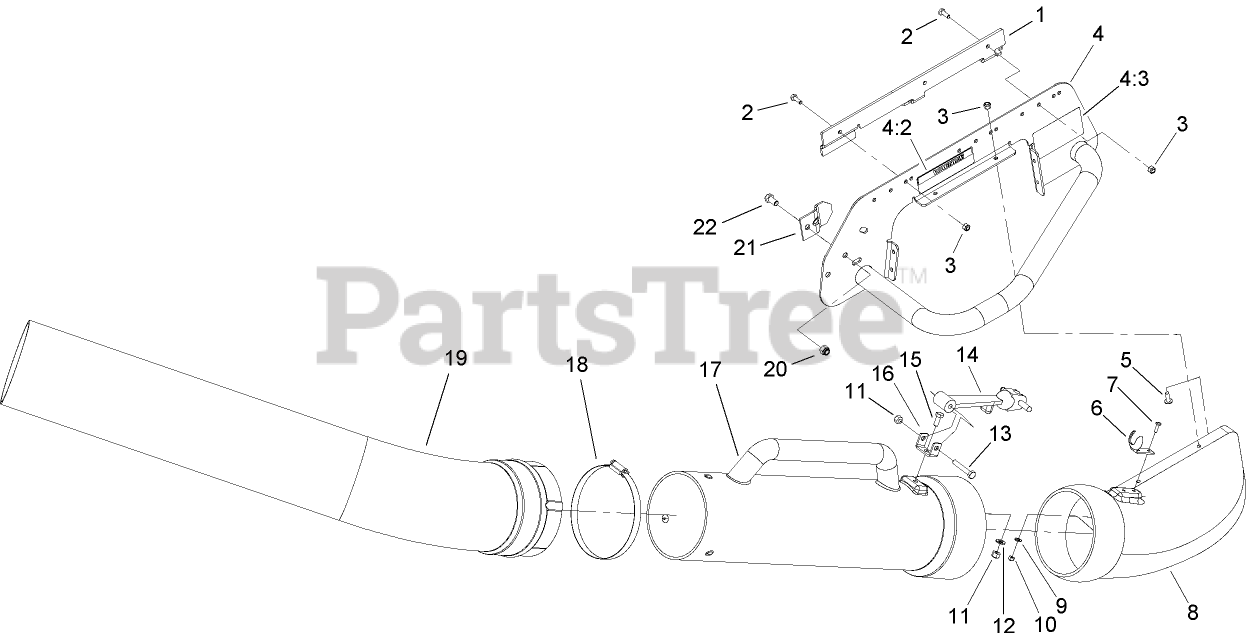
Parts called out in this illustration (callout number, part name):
1	BRACKET-MOUNTING
2	SCREW-HH
3	NUT-LOCK, NI
4	MOUTING PLATE ASM
4:2	DECAL-WARNING
4:3	DECAL-WARNING
5	SCREW-HEAD, TRUSS
6	BRACKET-HOOD
7	SCREW-PPH
9	WASHER-FLAT
10	NUT-LOCK, NI
11	NUT-LOCK, NI
12	WASHER-PLAIN
13	SCREW-HH
14	HOLDDOWN-HOOD
15	SCREW-HH
16	BRACKET-ANCHOR
17	TUBE-STRAIGHT
18	CLAMP-HOSE
19	TUBE-ELBOW
20	NUT-LOCK, NI
21	Bracket-Clamp
22	SCREW-HH
